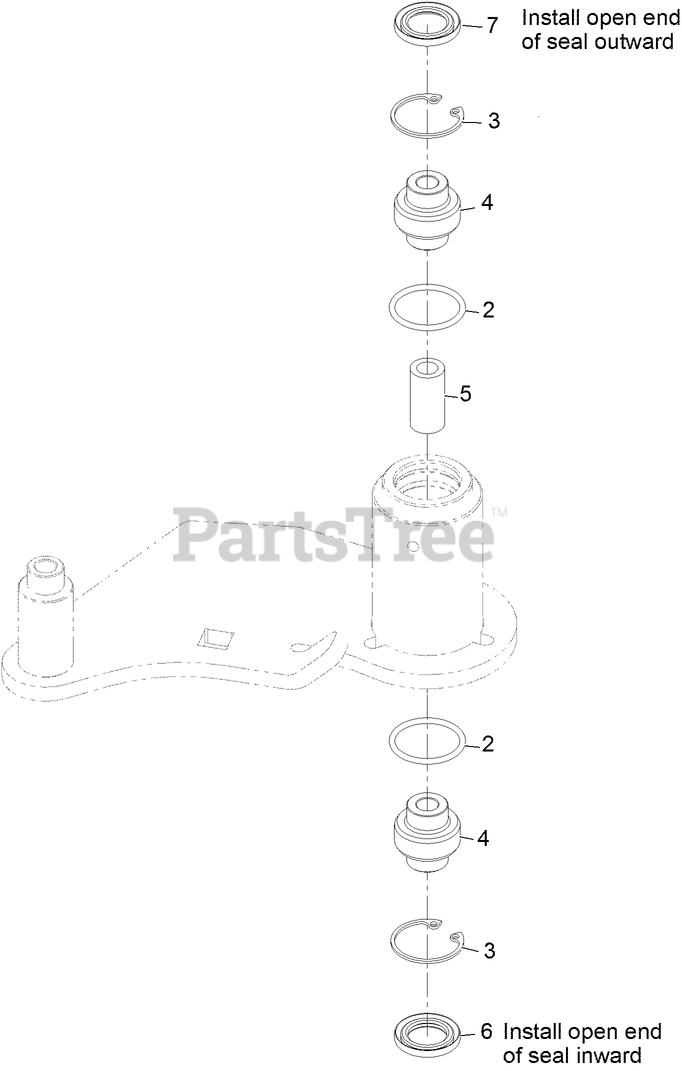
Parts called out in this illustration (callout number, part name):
2	O-RING
3	RING-SNAP
4	BEARING-SPHERICAL
5	SPACER
6	SEAL-LIP, DOUBLE
7	SEAL-LIP, SINGLE
